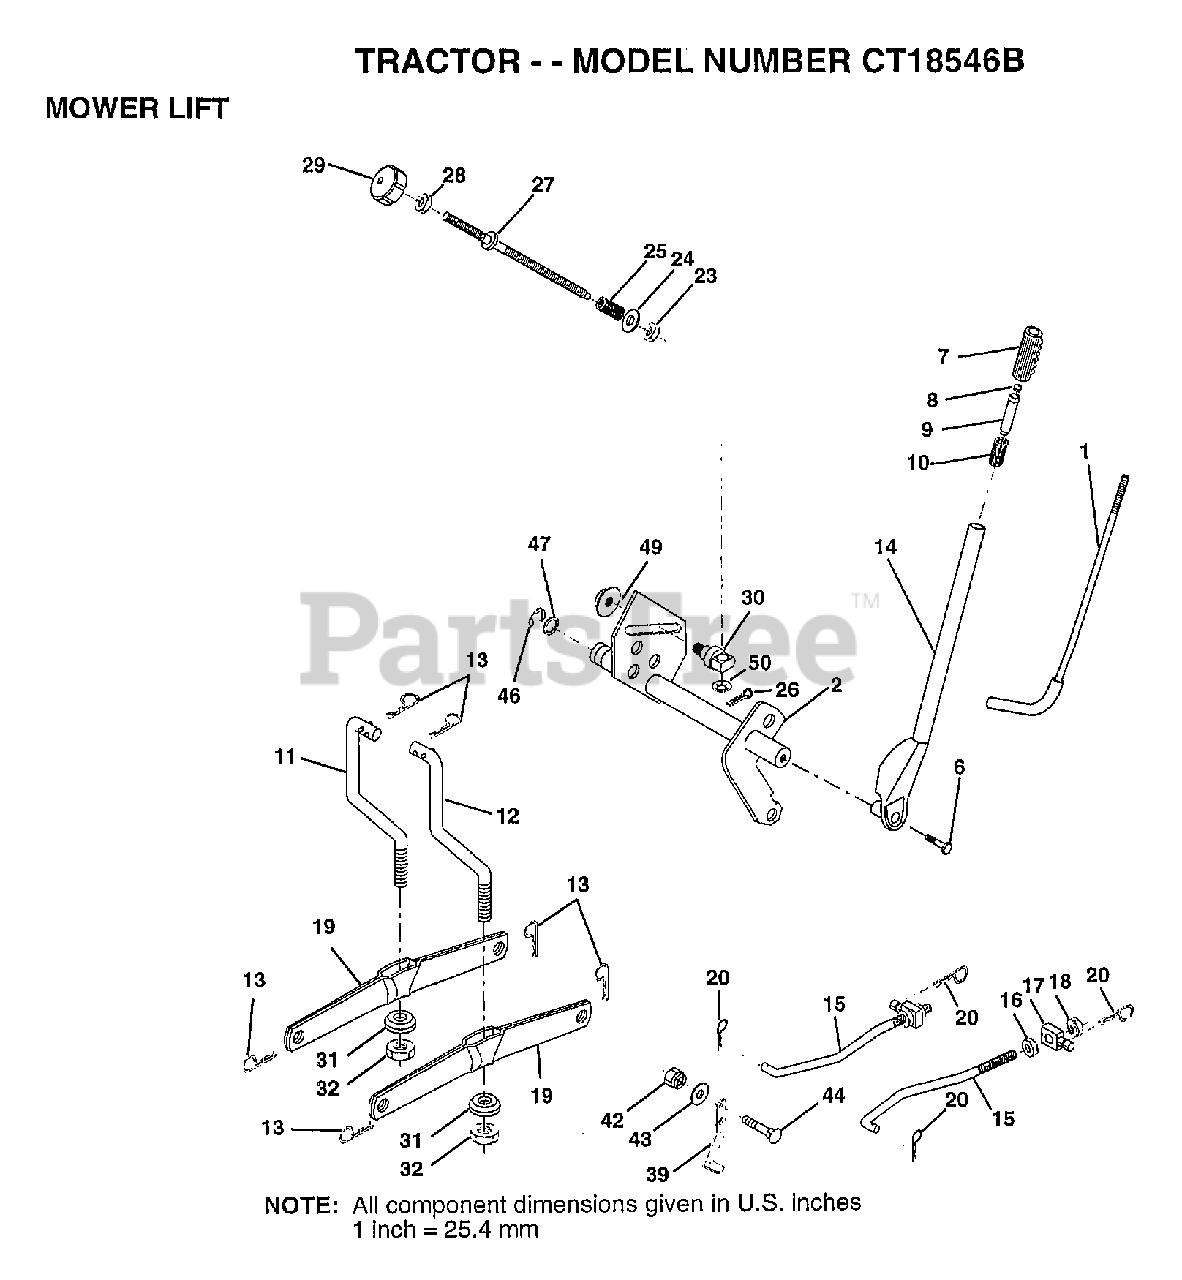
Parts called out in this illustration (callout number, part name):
1	LEVER ROD LT
2	SHAFT LIFT W/IND
6	"BOLT,HEX"
7	GRIP
10	SPRING T
11	LINK.LIFT.LH.GTV
12	LINK.LIFT.RH.GTV.
15	LINK.FRONT
16	NUT
17	TRUNION
18	NUT.LK.W/WSH.1/2.
19	ARM SUSP REAR
20	RETAINER.SPRING
23	NUT T
24	WASHER
25	SPRING.COMP.INF.H
27	ROD.ADJ.LIFT
28	NUT
29	KNOB INF 3/8-16
30	TRUNNION
31	BEARING PVT LH
32	NUT.CROWNLOCK.3/8
39	STOP.OVER.CENTER
43	WASHER GT
44	BOLT
46	E-RING
47	WASHER
49	NUT.HXFLG.LOCK.
50	NUT PUSH M
